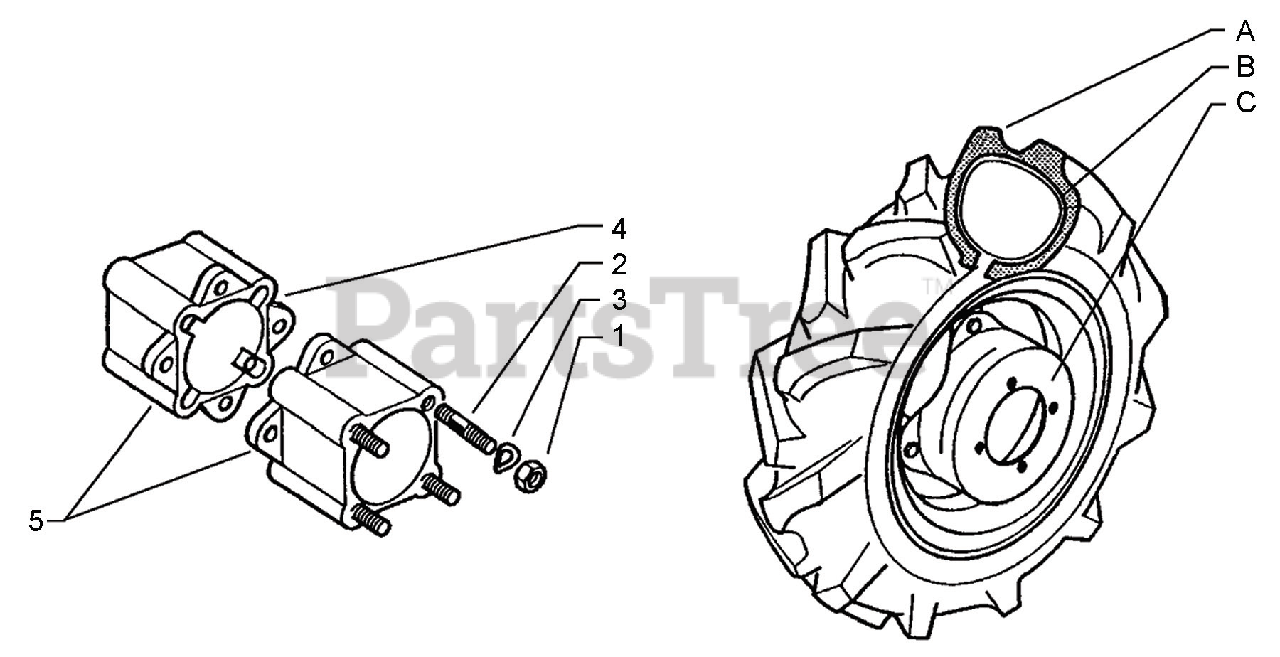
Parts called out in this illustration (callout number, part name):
1	NUT, M10
2	STUD, M10X40X24X12
3	WASHER, M10.5
5	PAIR WHEEL EXTENSIONS, INCLUDES 4 & 5
A	TIRE 3.50 - 8"
A	TIRE 4.00 - 8"
A	TIRE 4.00 - 10"
A	TIRE 5.00 - 10"
A	TIRE 5.00 - 12"
A	TIRE 6.50 - 12"
B	TUBE 3.50 - 8"
B	TUBE 4.00 - 8"
B	TUBE 4.00 - 10"
B	TUBE 5.00 - 10"
B	TUBE 5.00 - 12"
B	TUBE 6.50 - 12"
C	RIM 3.50 - 8" & 4.00 - 8"
C	RIM 4.00 - 10" & 5.00 - 10"
C	RIM 5.00 - 12" & 6.50 - 12"
D	PAIR WHEELS COMPLETE - 15 X 3.50 - 8"
D	PAIR WHEELS COMPLETE - 16 X 4.00 - 8"
D	PAIR WHEELS COMPLETE - 18 X 4.00 - 10"
D	PAIR WHEELS COMPLETE - 19 X 5.00 - 10"
D	PAIR WHEELS COMPLETE - 22 X 6.50 - 12"
D	PAIR WHEELS COMPLETE - 22 X 5.00 - 12"
